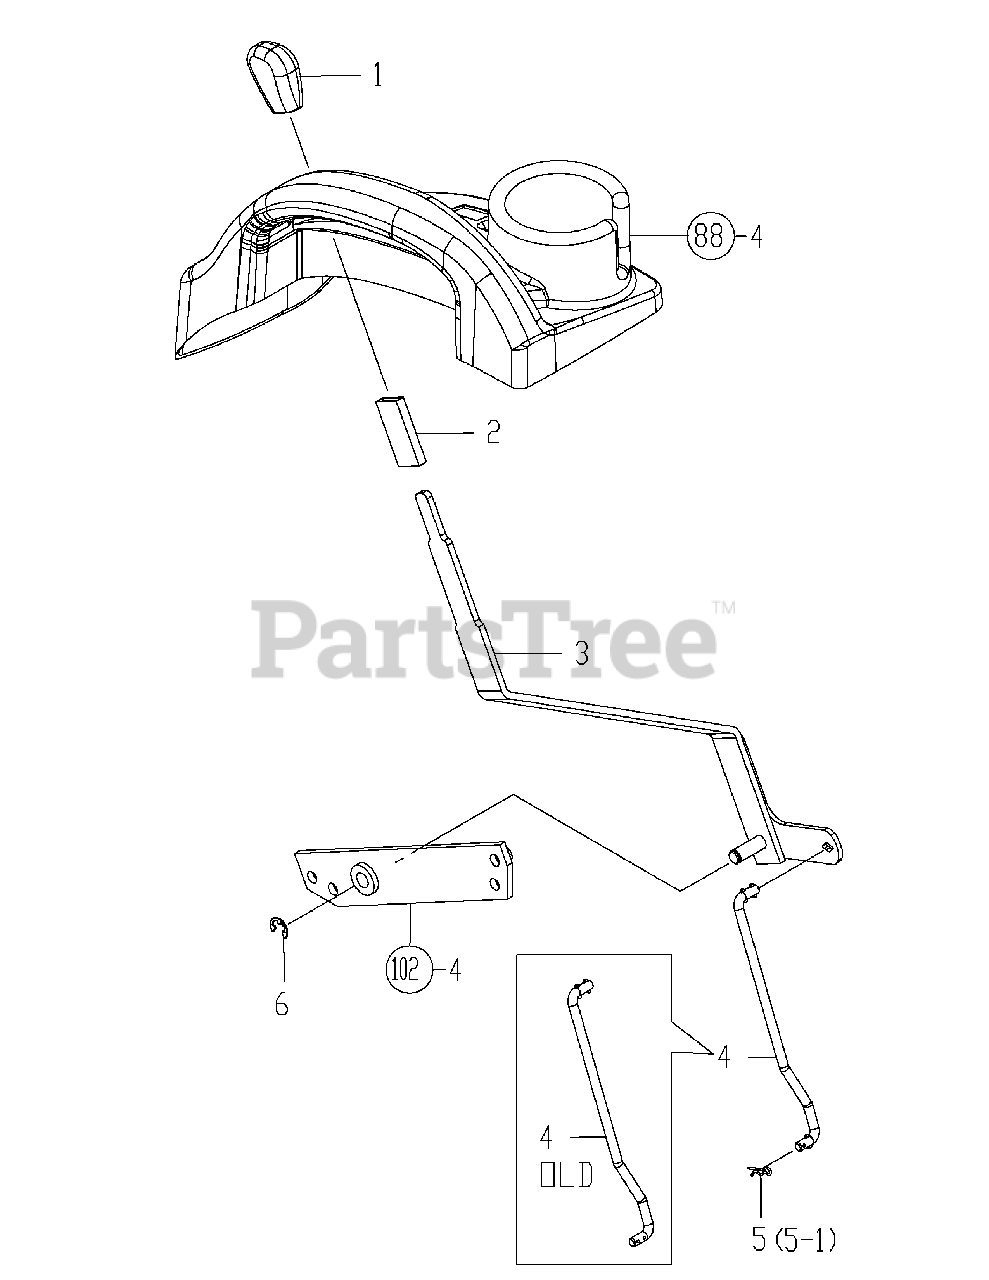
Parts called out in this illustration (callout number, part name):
1	KNOB, YELLOW
2	TUBE, PROTECTIVE
3	LEVER CMP, PTO
